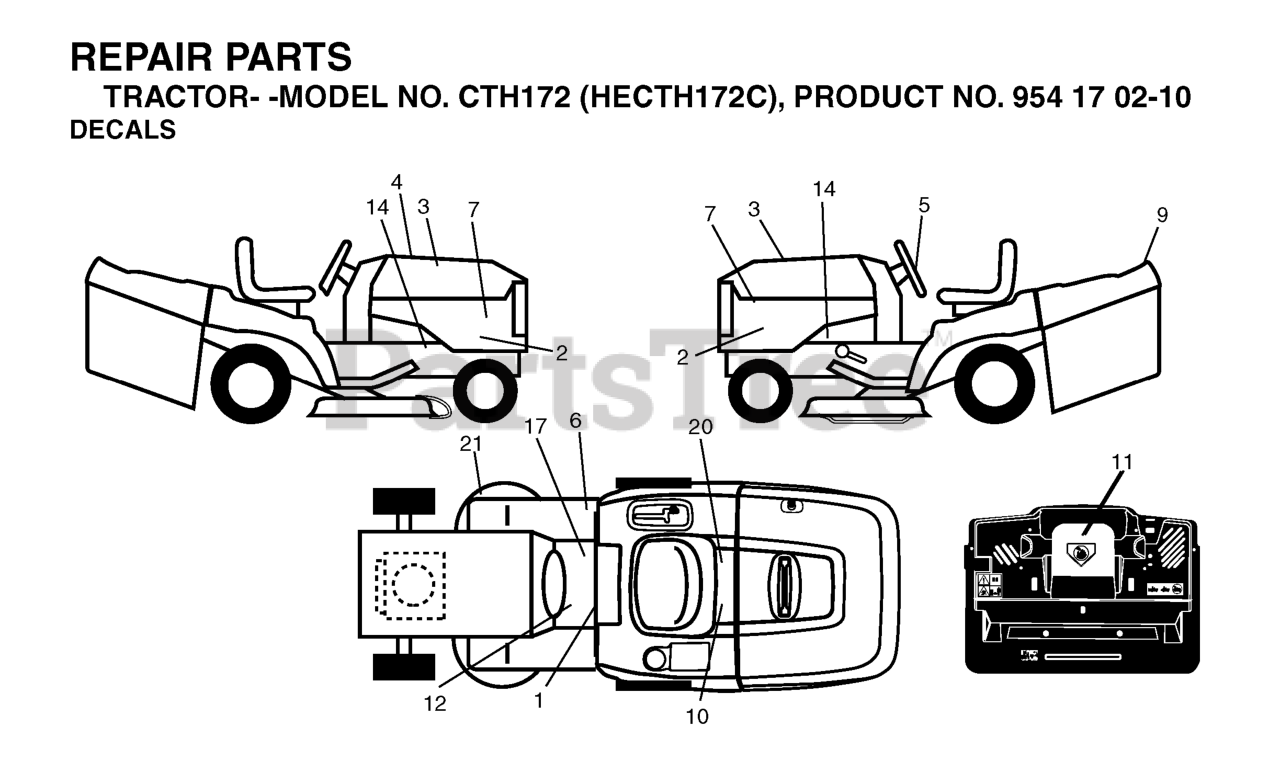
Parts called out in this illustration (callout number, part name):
1	DECAL READ OWNER'S MAN SYMS
5	DECAL.STEERING.HUSQ.BLUE
6	Decal, Fender 100 DB/CE
7	DECAL.HOOD.HUSQVARNA.INTERNATI
10	DECAL BTRY SYMBOLS
11	DECAL.INTERNATIONL.CUTFINGER
12	DECAL
17	DECAL PARK BRAKE
20	DECAL.BYPASS.FENDER.CRD.LT.YT
